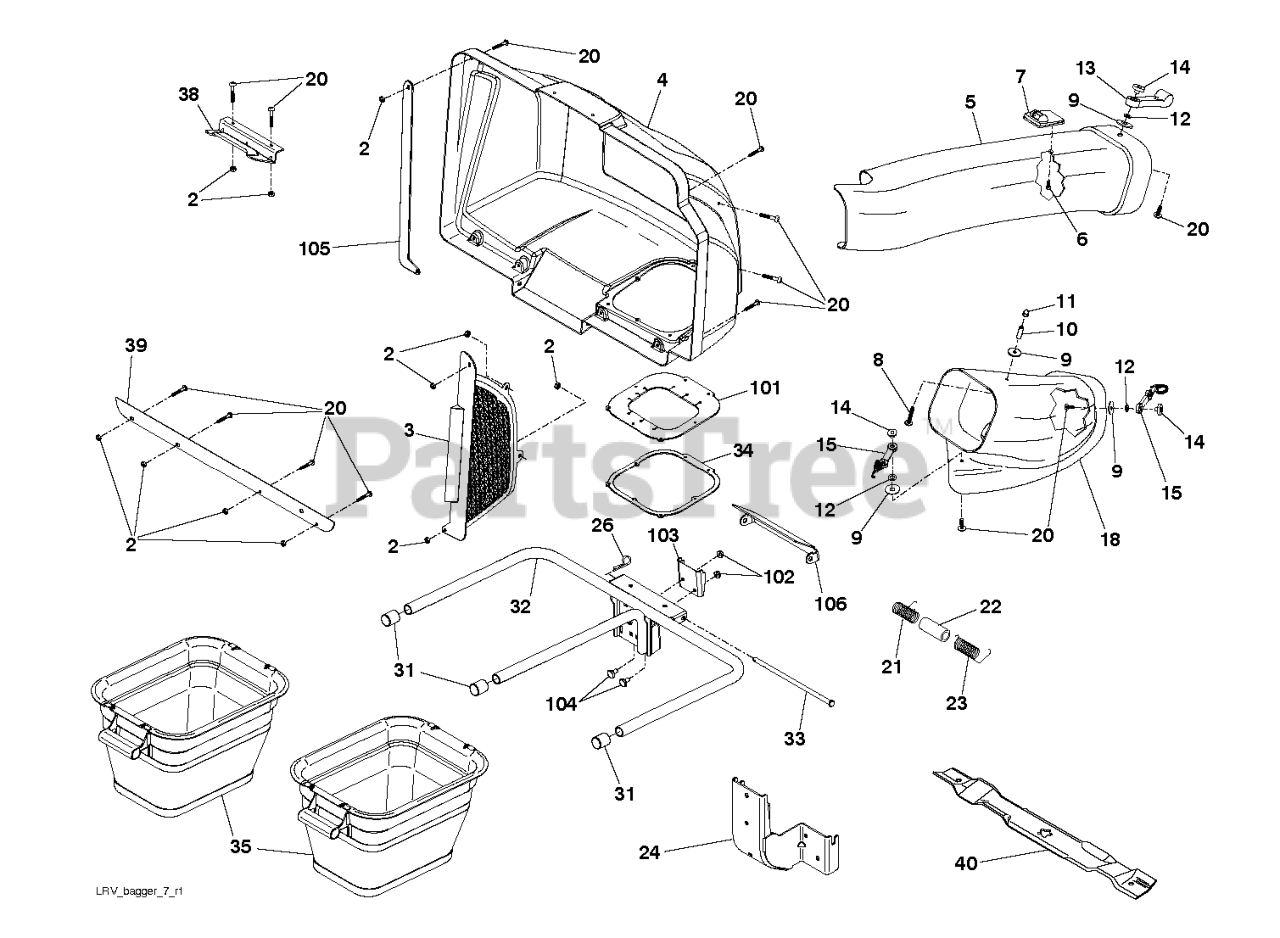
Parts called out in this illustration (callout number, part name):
3	COVER SCREEN
4	COVER.TOP.GENERIC.
5	CHUTE.UPPER.30" LRV(B)
7	INDICATOR ASM BAG
8	SCREW
9	RP STEEL WASHER
10	SPACER, SPLIT
11	NUT
12	LOCKWASHER #10
13	LATCH.HOOD.
14	WELDNUT
15	LATCH ASSY
18	CHUTE.LOWER.30" LRV(B)
20	SCREW
21	SPRING COVER LH
22	SPACER.COVER.BAGGER
23	SPRING COVER RH
24	ASM.SUPPORT.BAGGER
26	RETAINER-SPRNG RB
31	PLUG, TUBING END
32	FRAME.ASM.BAGGER.2BIN.QC42B
33	BAGGER.HINGE.PIN
34	GASKET.COVER.BAGGER.
35	SOFT.BAG.ASSEM.G30LRV
38	LATCH CER38
39	STRIP.REINFORCE.BAGGER.2BIN.BL
40	BLADE, MULCH.LRV30
101	GASKET.COVER.BAGGER.
102	NUT LOCK HEX FLANGE 5/16-18
104	BOLT.SHOULDER.1/2X12
105	SEAL.SIDE.LRV.L
106	BAGGER SPRING BRACKET
